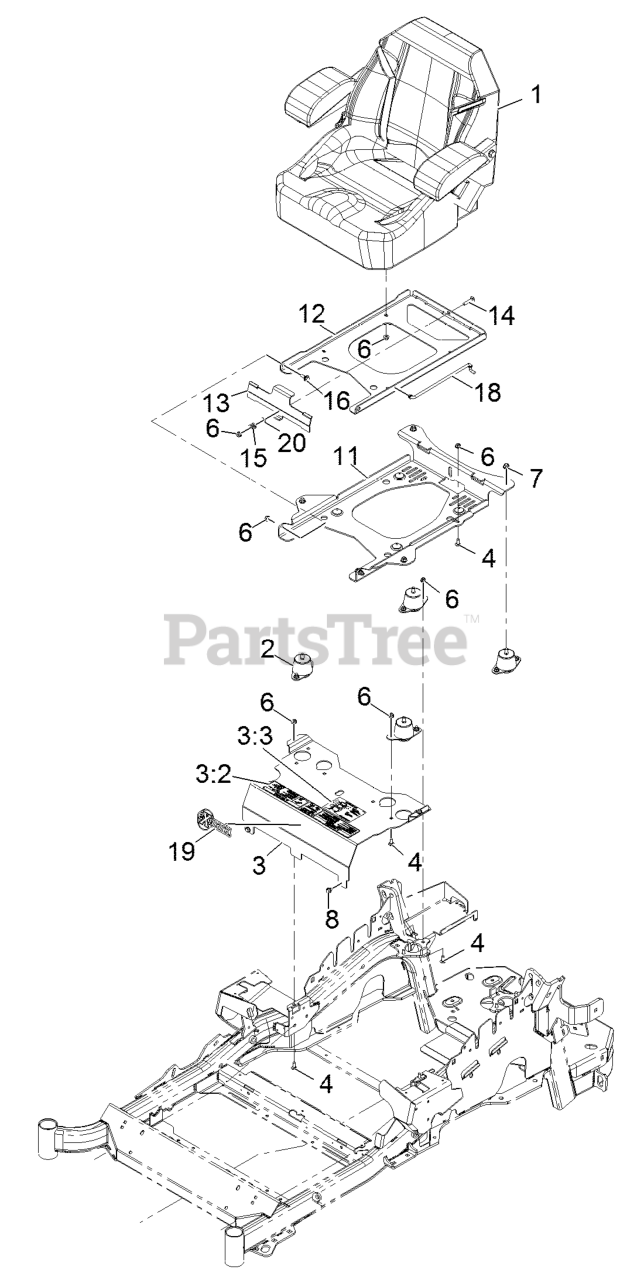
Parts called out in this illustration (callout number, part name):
2	ISOLATOR-SEAT
3	MOUNT-SEAT
3:2	DECAL-CONSOLE
3:3	DECAL-SERVICE AID
4	SCREW-CARR
6	NUT-HF, NI
7	NUT-HF, NI
11	PLATE-TILT, SEAT SUPPORT
12	PLATE-FRAME, SEAT
13	PLATE-LATCH, SEAT
14	BOLT-CARR
15	SPRING-COMPRESSION
16	SCREW-SHOULDER
18	ROD-PROP
20	WASHER-PLAIN
